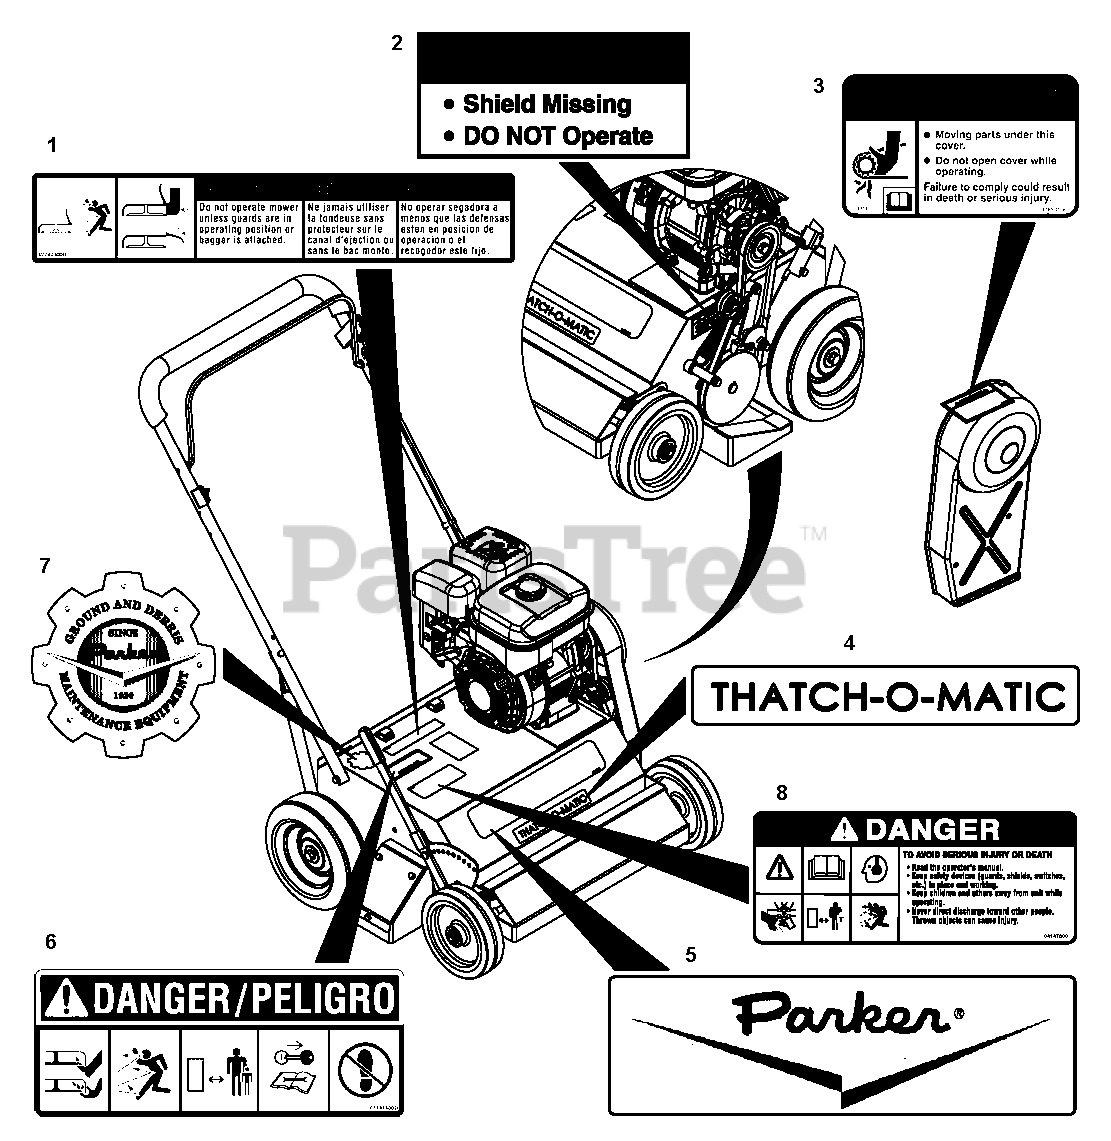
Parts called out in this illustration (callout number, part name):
1	Decal, Warning
2	Decal, Warning, Shield
3	Decal, Warning, Moving Parts
4	Decal, THATCH-O-MATIC
5	Decal, Parker Logo
6	Decal, Mower Pan Danger
7	Decal, Parker Heritage, Small
8	Decal, Danger Read Manual
